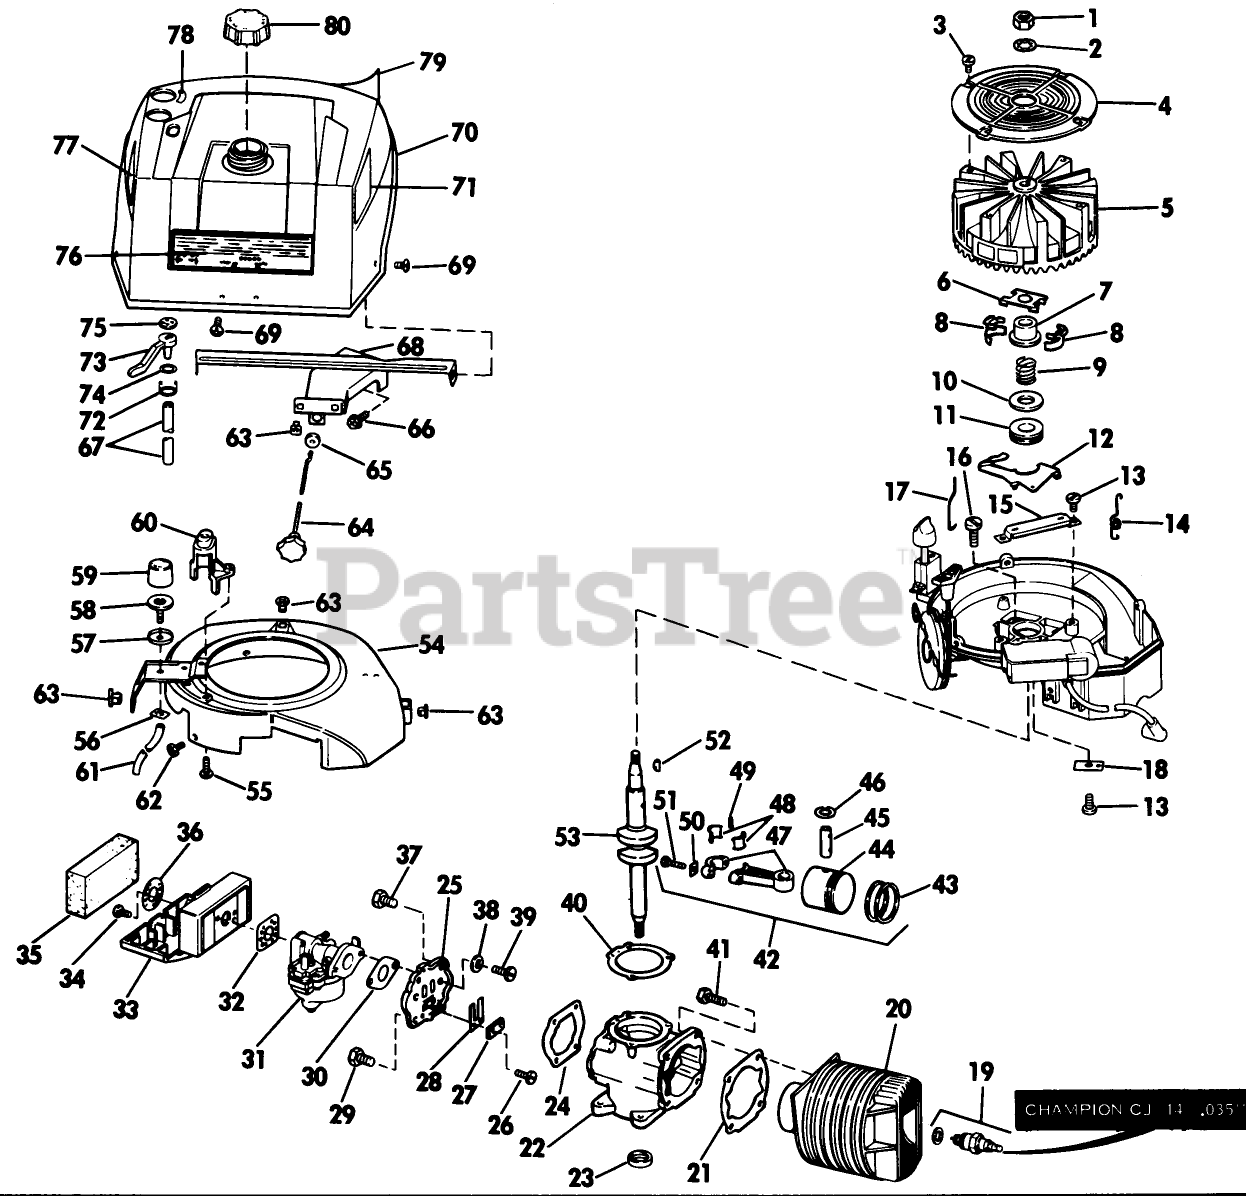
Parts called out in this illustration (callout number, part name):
3	SCREW F
7	COLLAR S
9	SPRING S
12	LEVER-GOVERNOR S
13	SCREW S
15	BRACKET
19	Spark Plug-Champion CJ-14 .035" Gap
21	GASKET S
25	REED PLATE AY. S
27	PLATE-BACKUP, REED
29	SCREW S
30	GASKET S
32	GASKET S
34	SCREW S
35	AIR FILTER S
36	WASHER S
37	SCREW S
40	GASKET S
46	RING-RETAINING
48	LINER ASM
56	LOCKNUT S
57	CUP-BULB
63	NUT-CLIP
66	SCREW S
68	BRACKET
69	SCREW S
74	WASHER S
